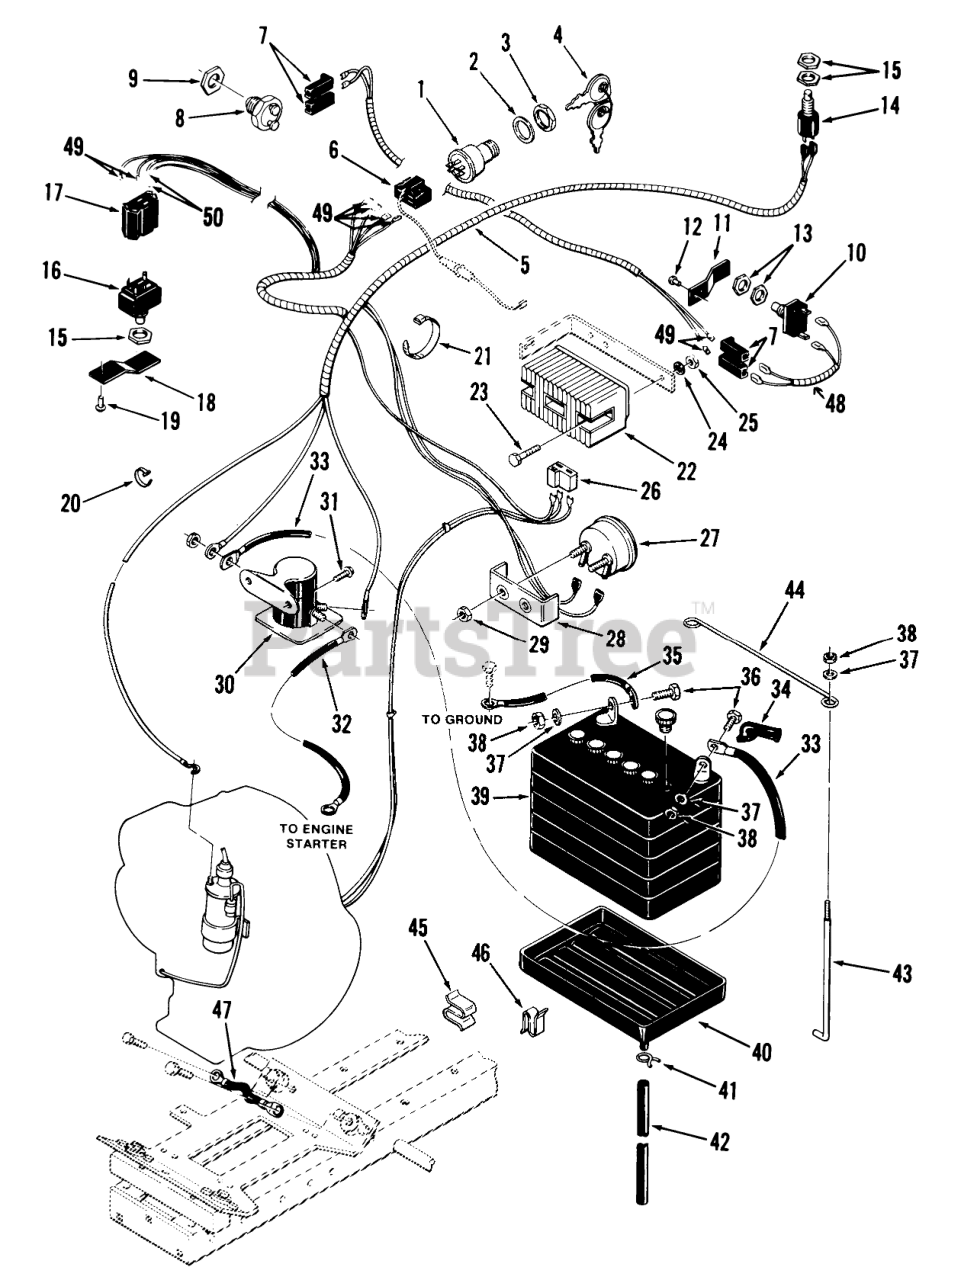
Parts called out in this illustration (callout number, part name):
1	SWITCH-IGNITION
7	Connector Housing Pedal Switch
9	NUT-SPECIAL 9/16-18
13	NUT-HEX
14	SWITCH
15	NUT-HEX
16	SWITCH-CLUTCH
17	CONNECTOR 5 WAY
22	REGULATOR-RECTIFIER
29	HEX NUT 10-32 E.S. + + USE 3296-21 + +
40	TRAY-BATTERY
44	ROD-HOLD DOWN
46	CLIP
50	TERMINAL-TAB RCPT
